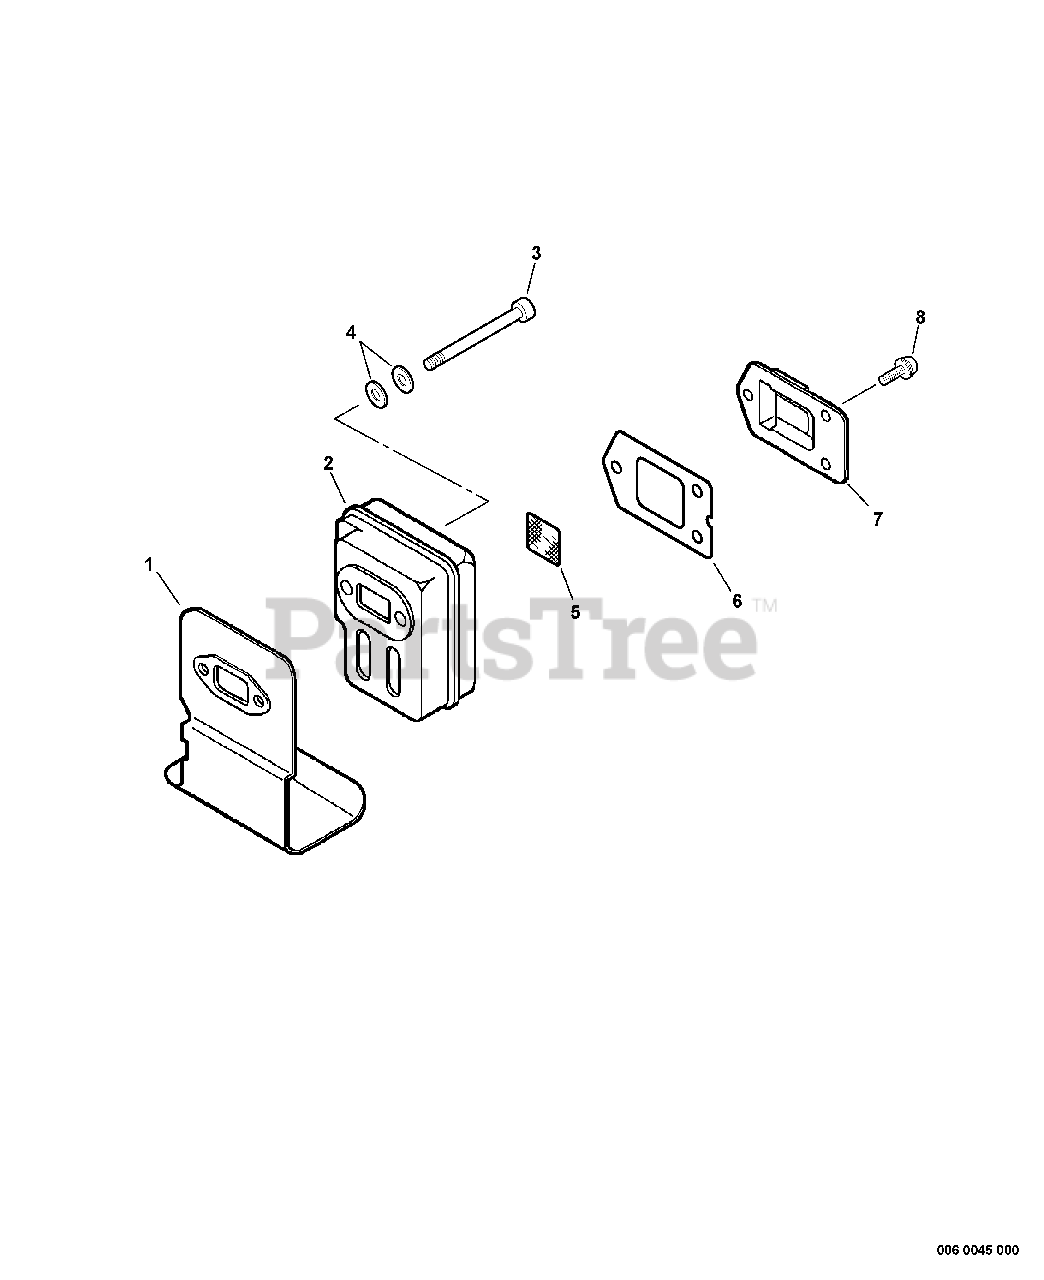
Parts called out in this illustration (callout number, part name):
1	SHIELD, EXHAUST
3	BOLT M5×50
4	WASHER, FLAT 5.5×10×0.8
5	SCREEN, SPARK ARRESTER
6	GASKET, EXHAUST
7	GUIDE, EXHAUST
8	SCREW 4×10
